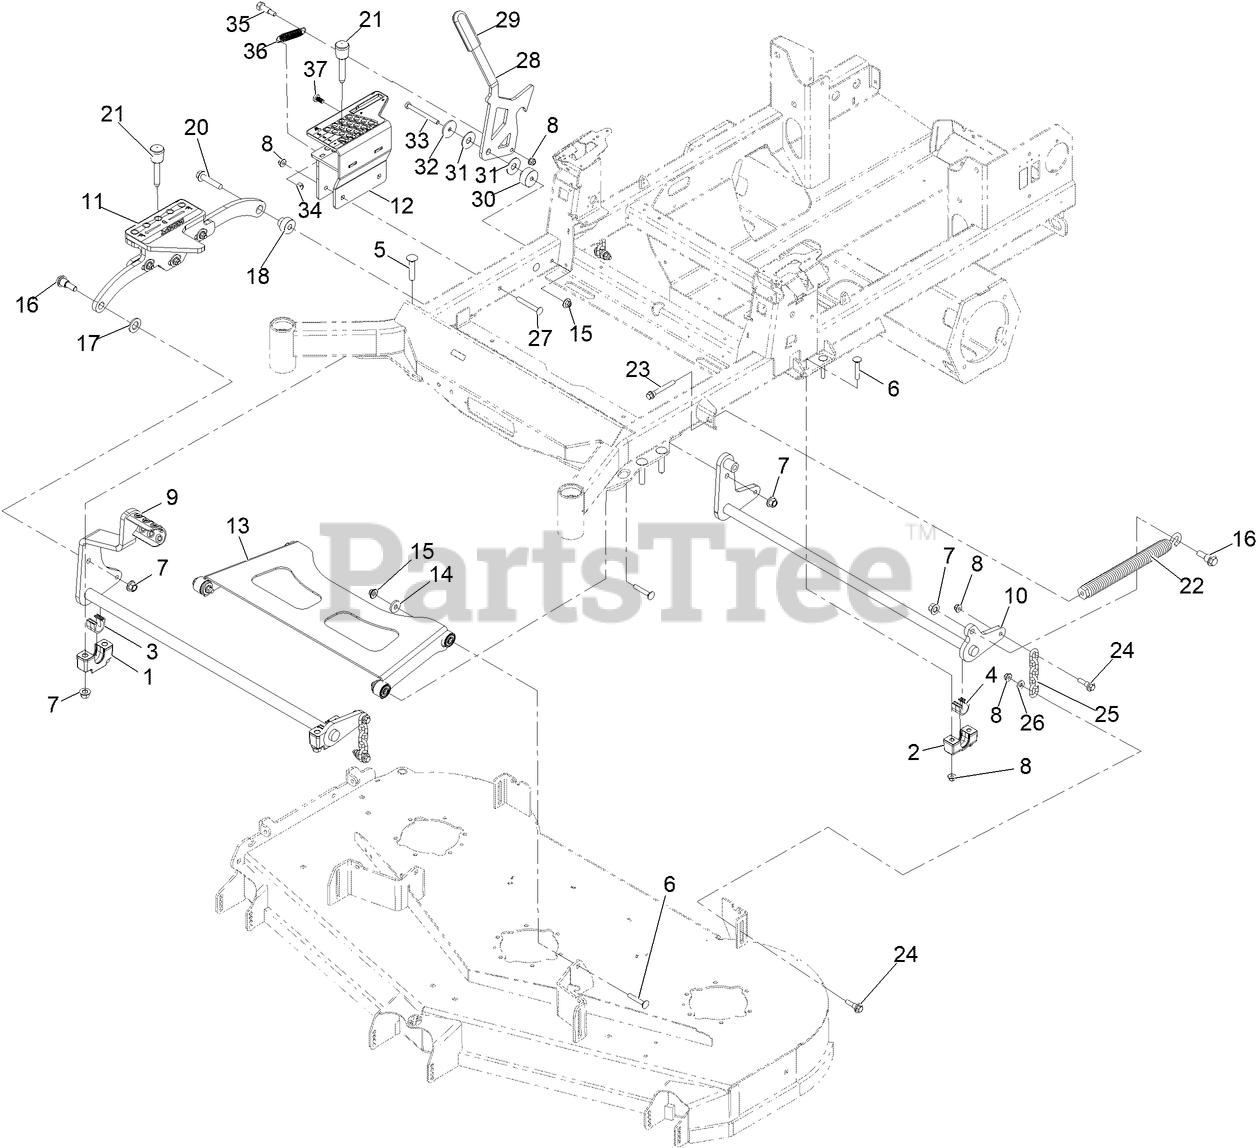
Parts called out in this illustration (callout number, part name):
1	SUPPORT-CROSS SHAFT, BEARING
2	SUPPORT-CROSS SHAFT, BEARING REAR
3	BEARING-CROSS SHAFT, FRON
4	BEARING-CROSS SHAFT, REAR
5	Bolt-Carriage 1/2-13 X 2 1/2 Spl Neck
6	Bolt-Carriage 3/8-16 X 2 1/4
7	Nut-Lock 1/2-13
8	NUT-HF, NI
9	WELD-FRONT CROSS SHAFT
10	WELD-REAR CROSS SHAFT
11	ASM-Decklift Linkages
12	ASM-HOC Box W/Decal
13	DECK STRUT W/ BUSHINGS ASM
15	Nut-Nyloc 3/8-16 Flg
16	SCREW-SHOULDER, HHF 1/2-13 X 1.12
17	WASHER-FLAT
18	SPACER-STEPPED
20	SCREW-HHF
21	ASM- HOC PIN
22	SPRING-EXTENSION
23	BOLT-SHOULDER
24	BOLT-SHOULDER
25	CHAIN-LIFT, DECK
27	SCREW-CARR
28	LATCH-TRANSPORT
29	GRIP-LEVER
30	SPACER-STEPPED
32	WASHER-REBOUND
33	SCREW-HH
34	Nut-Lock, NI
35	SCREW-SHOULDER, HH
36	SPRING-EXTENSION, PIVOT
37	MAGNET-STUD, THREADED
